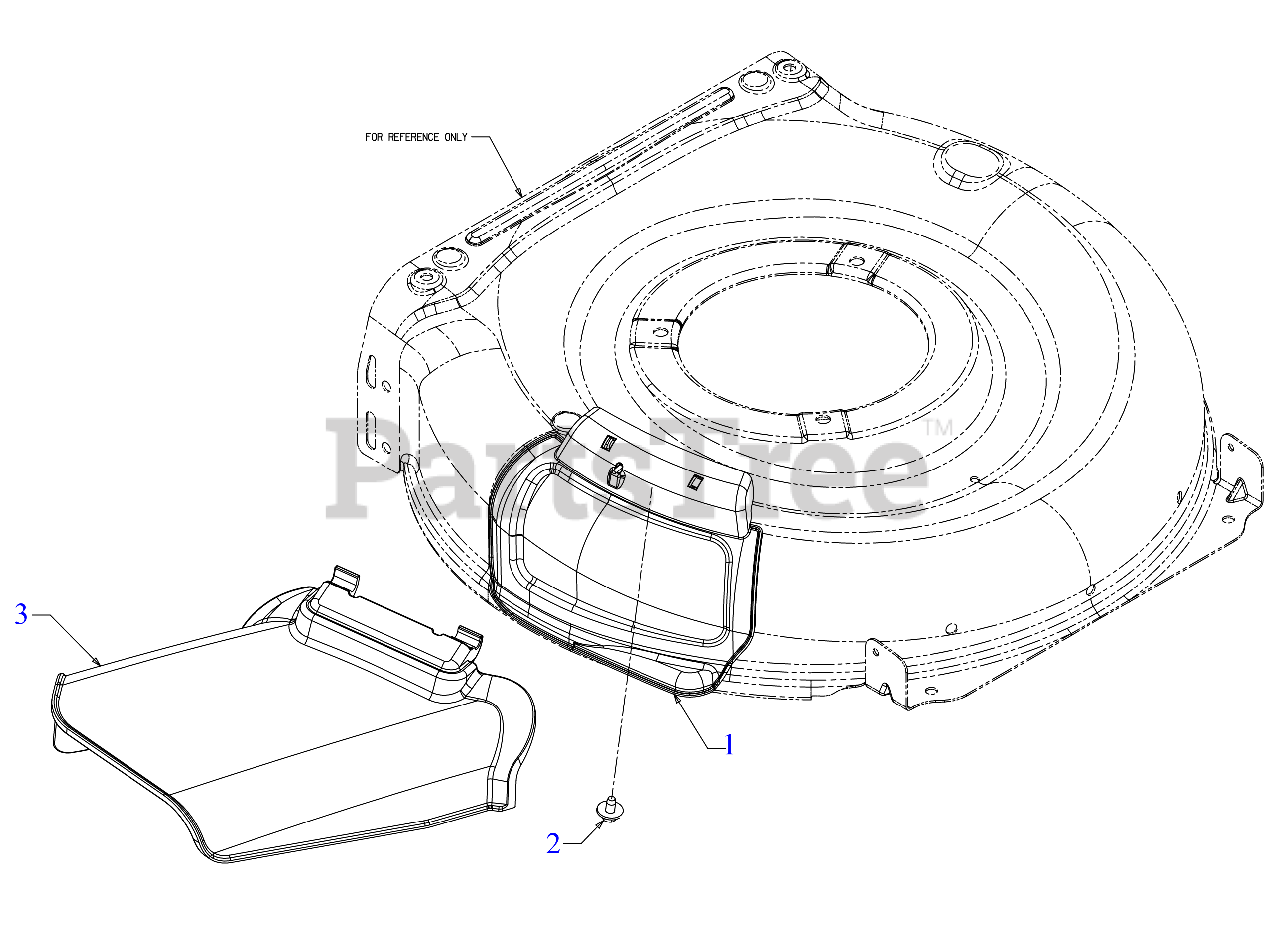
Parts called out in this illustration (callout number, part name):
1	MULCH PLUG ASSEMBLY
2	SCREW 1/4-20 x .50
3	SIDE DISCHARGE CHUTE
